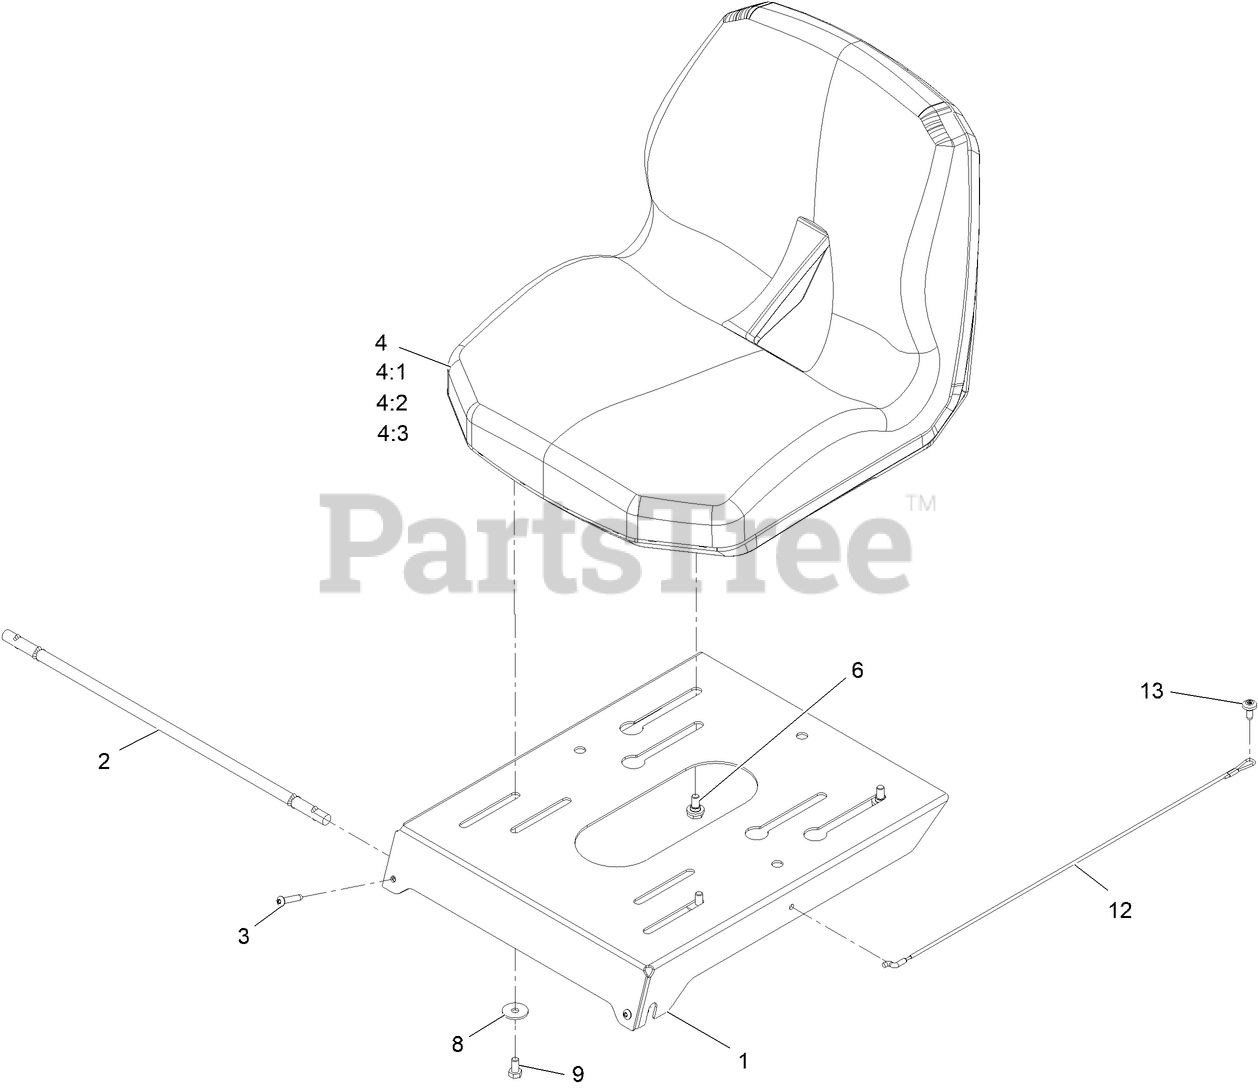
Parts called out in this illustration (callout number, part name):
2	ROD-PIVOT
3	SCREW-TTH, THREAD ROLLING
4	Seat-16 In
4:1	SEAT-16 IN
4:2	Cover-Seat
4:3	SWITCH-BAIL
6	BOLT-SHOULDER,HFH
8	WASHER-PIVOT
9	SCREW-HH
12	CABLE-LANYARD
13	SCREW-SHOULDER
